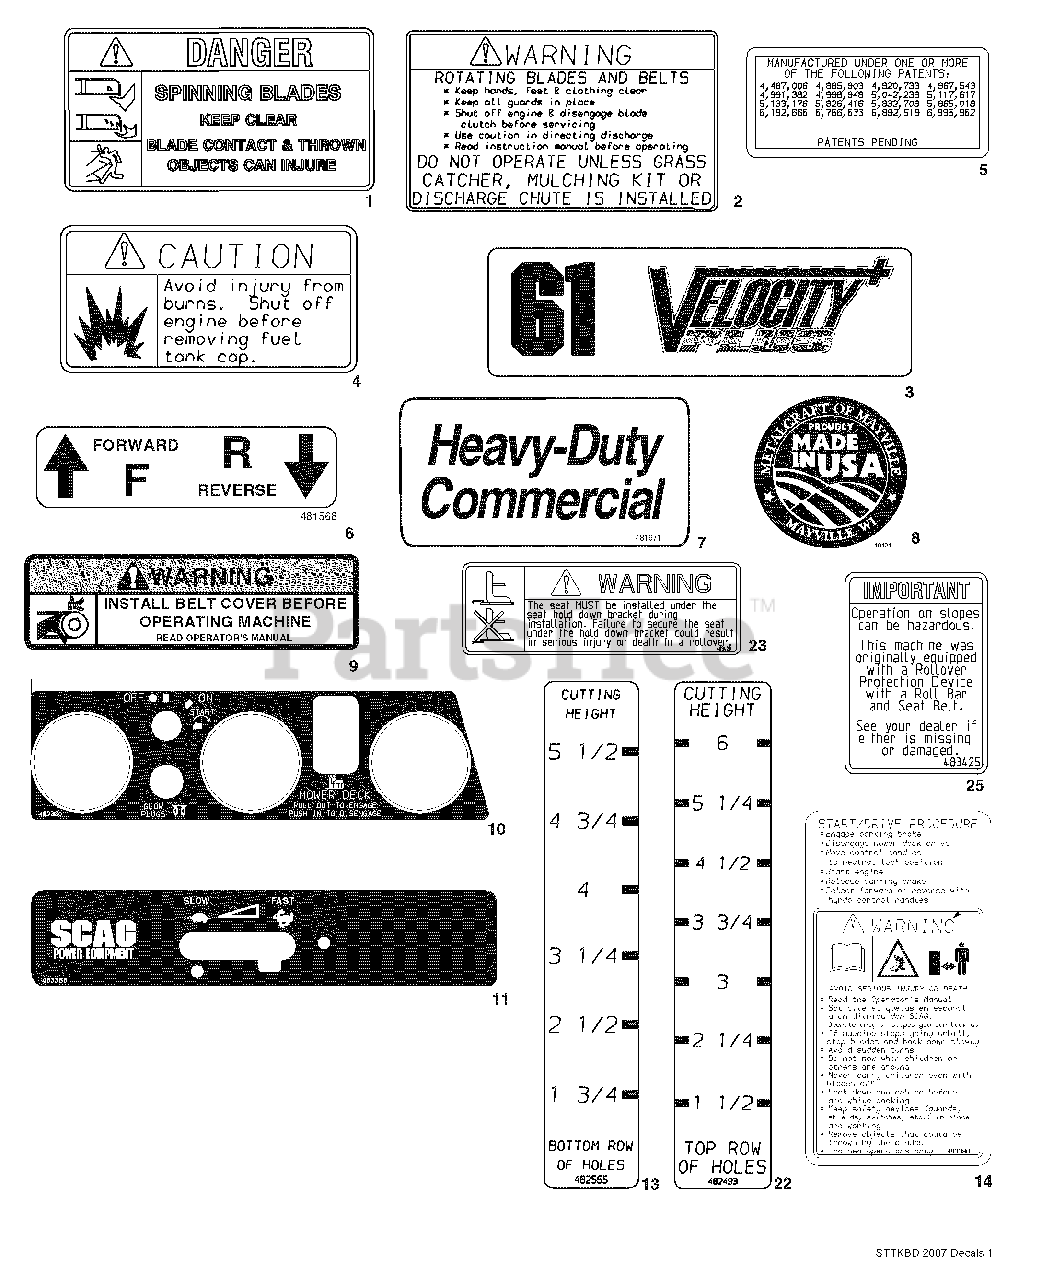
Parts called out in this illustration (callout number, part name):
1	Decal, Danger-Spinning Blades
2	Decal, Warning-Rotating Blades
3	Decal, 61 Velocity Plus
4	Decal, Fuel Tank
5	Decal, Patents
6	Decal, Traction Control
7	Decal, Heavy Duty Commercial
8	Decal, Metalcraft-Made In USA
9	Decal, Belt Cover
10	Decal, Instrument Panel-Upper
11	Decal, Instrument Panel - Lower
13	Decal, Cutting Height - Lower
14	Decal, Start/Drive Procedure
22	Decal, Cutting Height - Upper
23	Decal, Warning Seat Hold Down
25	Decal, ROPS
